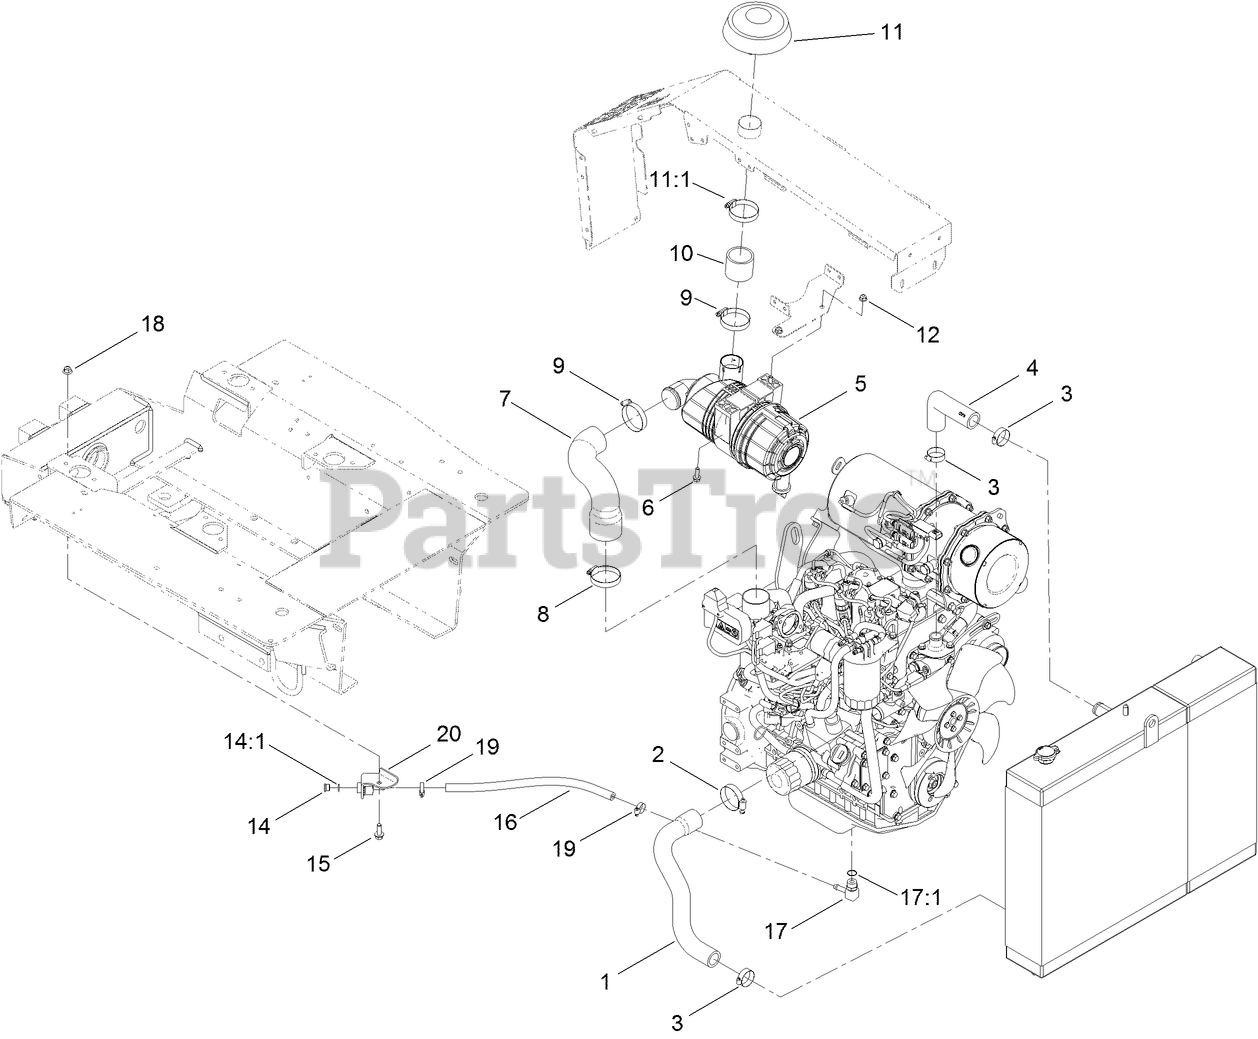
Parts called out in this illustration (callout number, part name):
1	HOSE-RADIATOR, LOWER
2	CLAMP-HOSE
3	CLAMP-HOSE
4	HOSE-RADIATOR, UPPER
5	AIR CLEANER ASM
6	SCREW-HHF
7	HOSE-AIR
8	CLAMP-HOSE
9	CLAMP-HOSE
10	HOSE-AIR INLET
11	RAIN CAP ASM
11:1	CLAMP-HOSE
12	NUT-HF, NI
14	PLUG-HEX, HOLLOW
14:1	O-RING
15	SCREW-HHF
16	HOSE-HYD
17	FITTING-BARBED-90
17:1	WASHER-SEAL, BONDED
18	NUT-HF, NI
19	CLAMP-HOSE
20	OIL PLUG ASM
